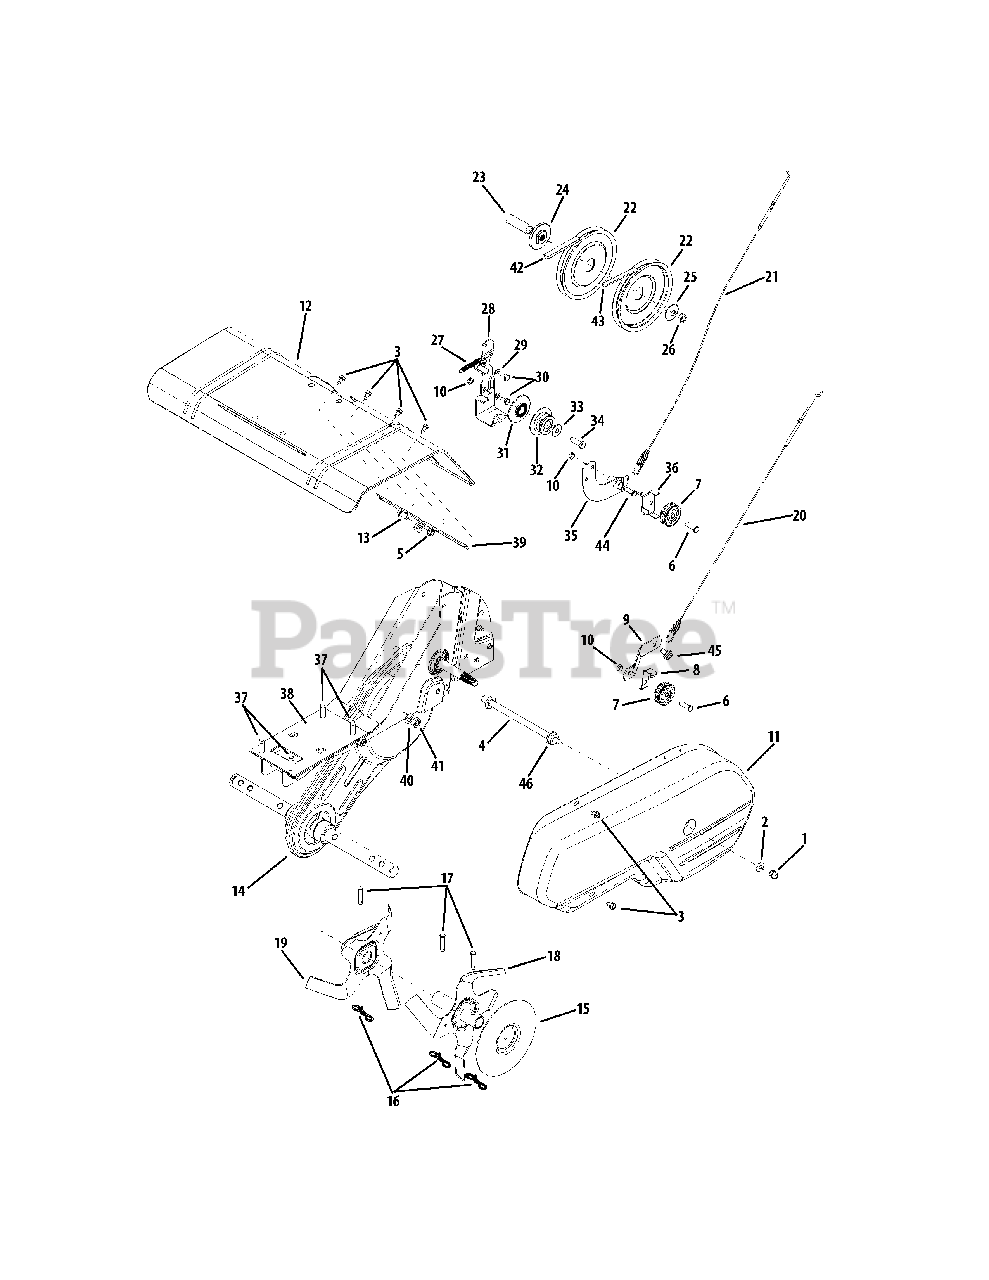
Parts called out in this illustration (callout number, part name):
1	Hex L-Stop Nut, 1/4-28
2	Flat Washer, 266" x .625"
3	Hex Washer TT-Tap Screw, 1/4-20 x .5"
4	Belt Cover Bolt
5	Hex Flange Top L-Nut, 5/16-18
6	Hex Head Screw, 3/8-16 x 1.25"
7	Flat Idler Pulley, 2.12"
8	Idler Belt Keeper
9	Idler Bracket
10	Hex Center Jam Nut, 3/8-16
11	Belt Cover
12	Tine Shield
13	Hex Head Cap Screw, 5/16-18 x .75"
14	Chain Case Assembly Complete
15	Outer Disc Plate Assembly
16	Cotter Pin, Bow Tie
17	Clevis Pin
18	Outer Tine Assembly, Left
18	Outer Tine Assembly, Right
19	Inner Tine Assembly, Left
19	Inner Tine Assembly, Right
20	Forward Clutch Cable
21	Reverse Clutch Cable
22	Flat Pulley, 6"
23	Spacer, .64" x 2.4"
24	Pulley Mounting Adapter
25	Bell Washer, 525" x 1.5"
26	Hex Jam Nut, 1/2-20
27	Return Spring
28	Reverse Bracket
29	Lock Washer, 5/16
30	Hex Bolt, 5/16-24 x .625"
31	Engine Inner Pulley
32	Reverse Engine Pulley
33	Bell Washer, .396" x 1/14"
34	Hex Bolt, 3/8-24 x 1.00"
35	Reverse Arm Assembly
36	Reverse Belt Keeper
37	Hex L-Washer TT-Tap, 3/8-16 x 1.25"
38	Engine Plate
39	Tine Shield Bracket
40	L-Washer, 7/16"
41	Hex Nut, 7/16-20
42	Forward Drive Belt, 1/2 x 41.9"
43	Reverse Drive Belt, 3/8 x 45.68"
44	Shoulder Screw, .498 x 1.445
45	Shoulder Screw, .560 x.165
46	Flangelock Nut, 5/16 - 18
